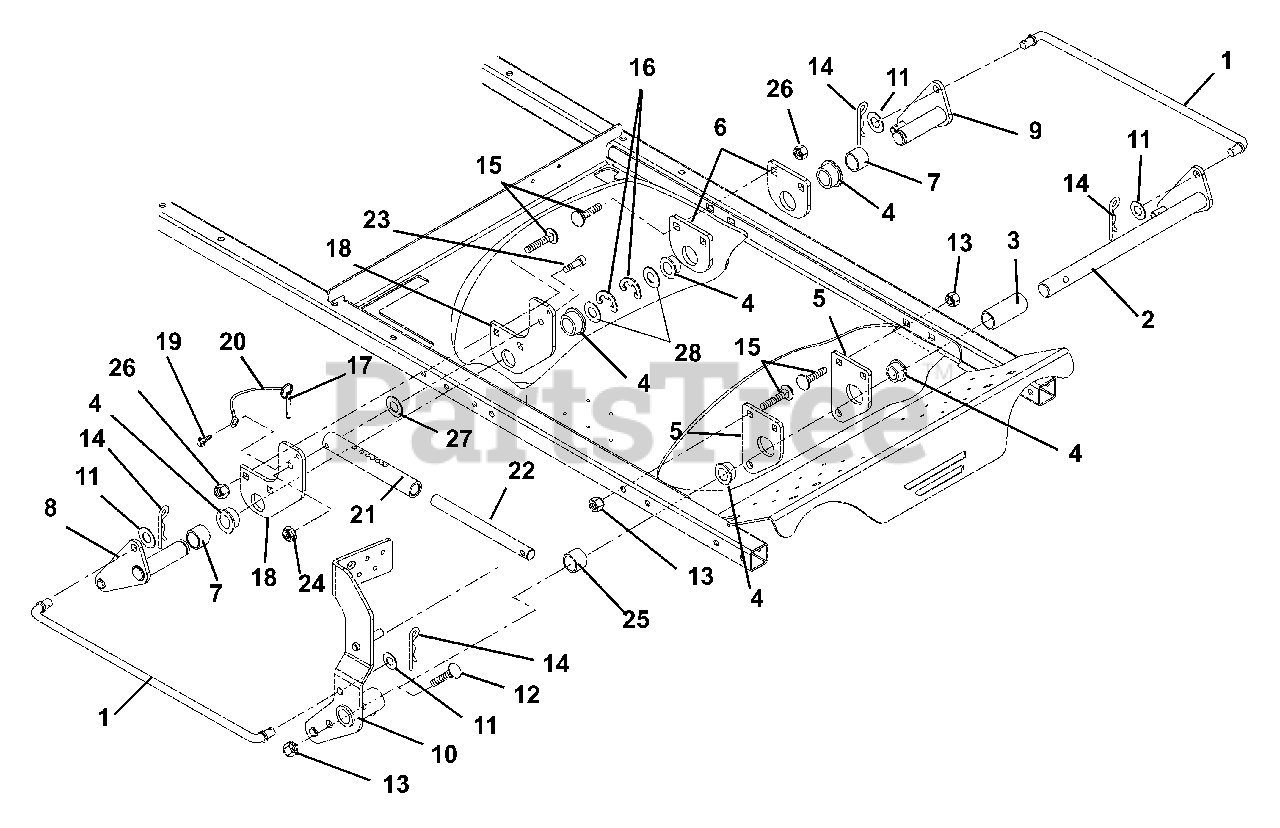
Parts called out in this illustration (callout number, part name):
1	Rod, Lift
2	Weldment, Front Lift
3	Bushing, Front
4	Bushing-Flange 1.00 x 1.12 x .62 x 1.50 Bronze
5	Bracket, Front Pivot
6	Bracket, Rear Pivot
7	Bushing, Rear
8	Weldment, Lift, Rear Right Hand
9	Weldment, Lift, Rear Left Hand
10	Weldment, Foot Pedal
11	Washer-Flat-Steel .531 x 1.06 x .095
12	Bolt, Hex .38-16 x 2.00 Grade 5
13	Nut .38-16 Flange Nyloc
14	Pin, Hair External
15	Bolt, Round Head Square Neck .38-16 x 2.50 Grade 5
16	Ring, Retaining .82 x 1.50 x .05
17	Pin, Spring Ball .375 O.D. x 1.50
18	Bracket, Rear Mount
19	Screw-Tapping .250-20 x .37 Hex Washer Head
20	Cable, Hood
21	Tube, Lift Stop
22	Rod, Lift
23	Bolt, Socket Head Screw .31 x 18 2.25
24	Nut, .312-18 Flange Nyloc
25	Spacer, Rear Lift
26	Nut-Locking-Top-Flange .38-16
27	Washer-Flat-Steel .390 x .75 x.125
28	Washer-Flat Steel 1.12 x 1.50 x .092
